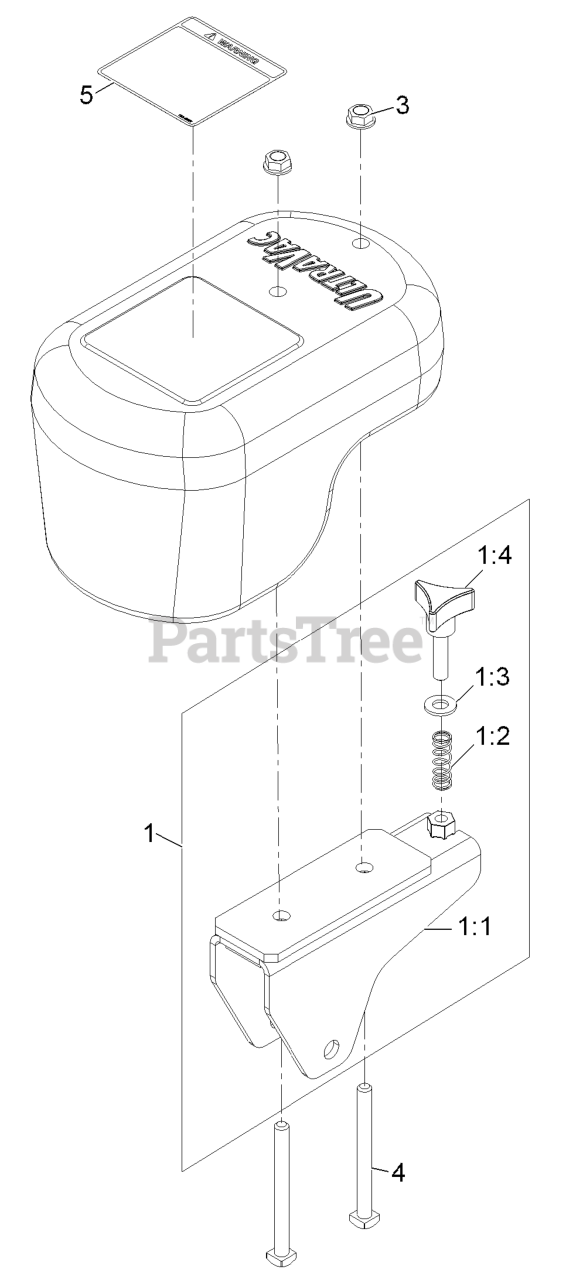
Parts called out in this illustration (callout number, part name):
1	ASM,CASTER WEIGHT BRACKET
1:1	WLD,CASTER WEIGHT BRACKET
1:3	WASHER-FLAT
3	NUT-HHF, WHIZ
4	BOLT, SQUARE HEAD YZ
5	DECAL,WEIGHT
